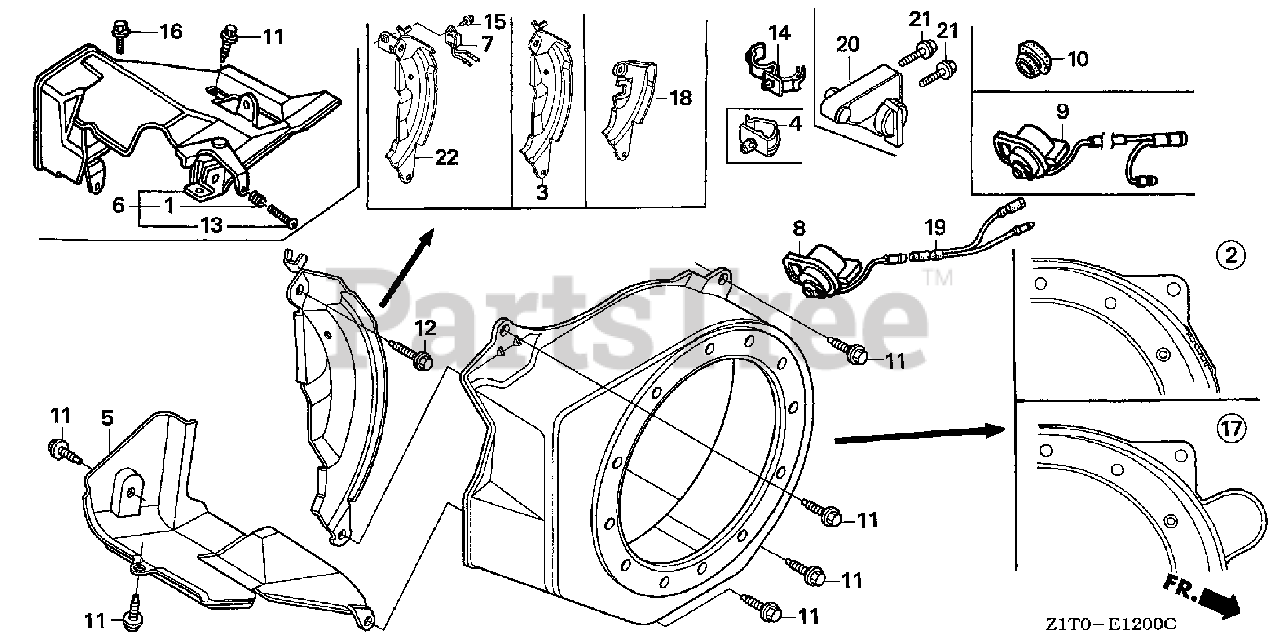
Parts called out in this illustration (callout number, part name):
2	COVER, FAN *NH1* (BLACK)
2	COVER, FAN *R280* (POWER RED)
7	ALERT UNIT, OIL
9	SWITCH ASSY., ENGINE STOP
11	BOLT, FLANGE (6X12) (CT200)
12	BOLT, FLANGE (6X20) (CT200)
14	CLIP, HARNESS
15	BOLT, FLANGE (6X8)
22	PLATE, SIDE (OIL ALERT)
